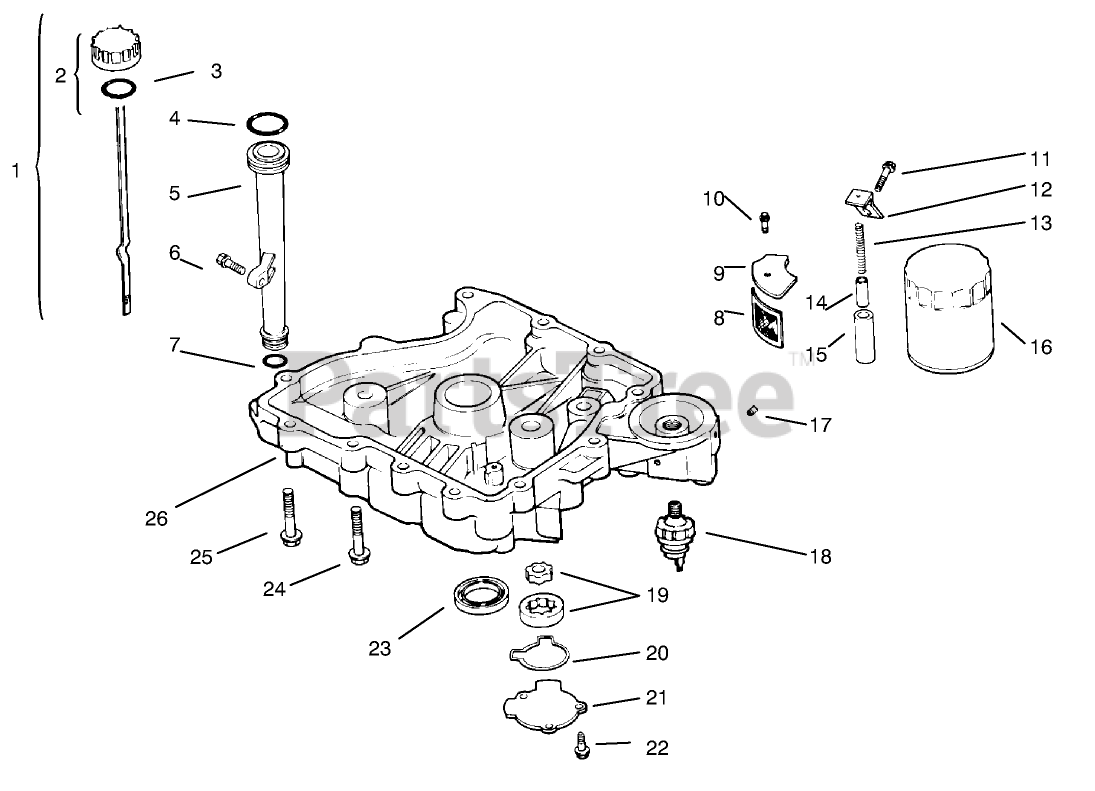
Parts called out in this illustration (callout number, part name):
1	Dipstick INC 2-3 (Only On: 72042, 72063, 72062, 72043)
2	Kit-Oil Fill Cap (Incl. Ref. #7)
3	ORing
4	O Ring-Upper Fill Tube (Only On: 72103)
5	Tube-Oil Fill (Only On: 72103, 72083)
7	O-Ring-Lower Fill Tube (Only On: 72042, 72063, 72062, 72043)
8	Screen-Oil Pickup
9	Cover-Oil Pickup Screen (Only On: 72042, 72063, 72062, 72043)
10	Screw M5x0.8x16 (Only On: 72042, 72063, 72062, 72043)
11	Screw M10x1.5x25 (Only On: 72042, 72063, 72062, 72043)
12	Bracket-Oil Pump Relief (Only On: 72042,72043,72062,72063)
13	Spring-Oil Relief Valve (Only On: 72042,72043,72062,72063)
14	Piston-Oil Relief Valve (Only On: 72042, 72063, 72062, 72043)
15	Body-Oil Relief Valve (Only On: 72042, 72063, 72062, 72043)
16	Filter-Oil
18	Switch-Oil Pressure
19	Pump-Oil (Only On: 72042, 72063, 72062, 72043)
20	O Ring-Oil Pump Cover (Only On: 72042,72043,72062,72063)
21	Cover-Oil Pump (Only On: 72042,72043,72062,72063)
22	Screw M5x0.8x16 (Only On: 72042, 72063, 72062, 72043)
23	Seal-Crankshaft (Only On: 72042, 72043, 72062, 72063)
25	Screw M8x1.25x45 (Only On: 72103, 72083)
26	Pan-Oil (Only On: 72042,72043,72062,72063)
